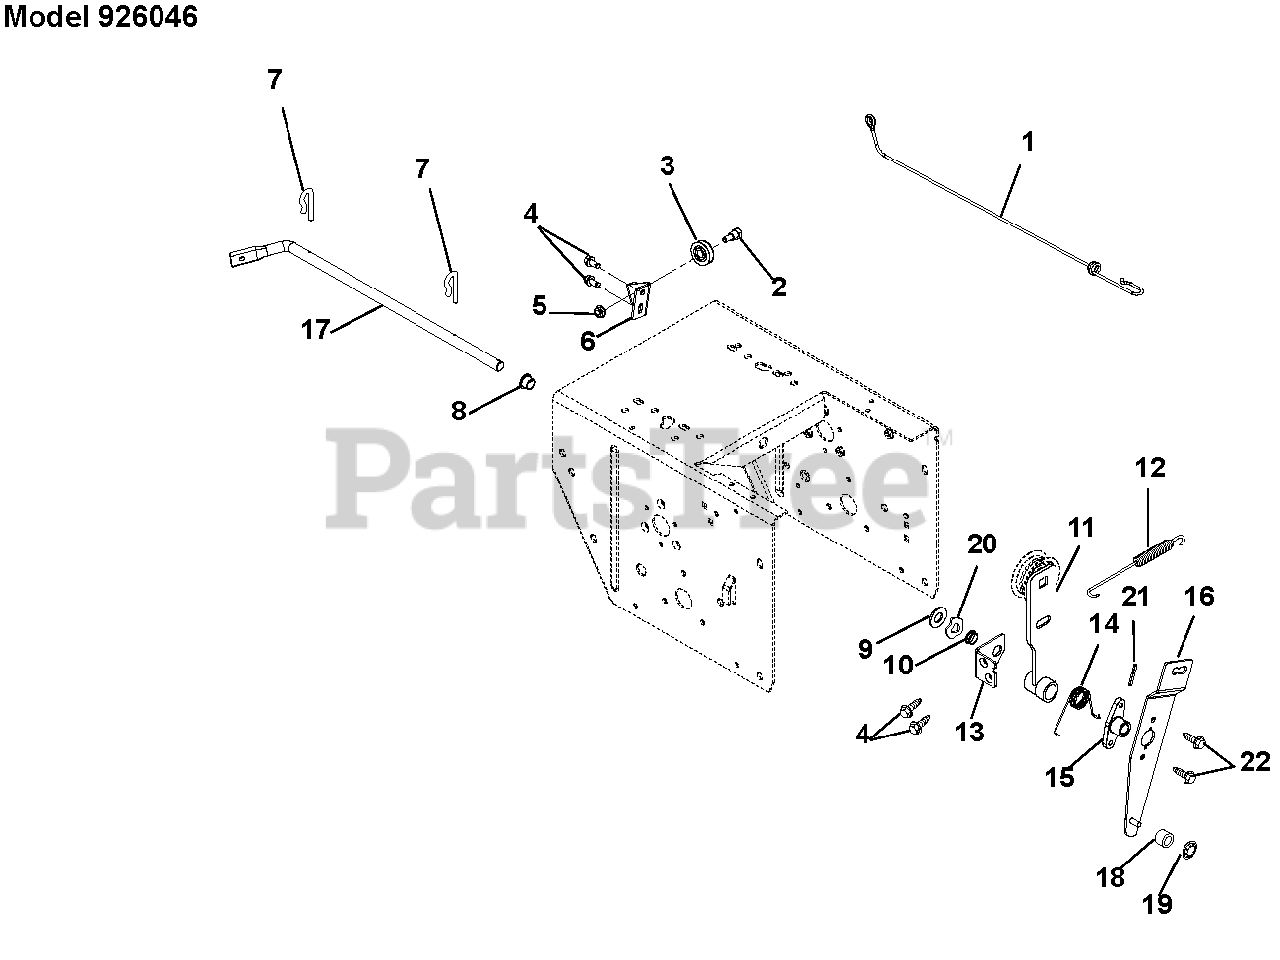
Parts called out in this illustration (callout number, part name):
2	Bolt, Shoulder
3	Pulley, Cable
4	Screw, Tapping Hex Washer Head Thread Rolling .25-20 x .50
5	Nut, Locking Top Flange .25-20
6	Bracket, Cable Pulley
7	Clip, Spring
8	Bushing, Polyliner
9	Washer, Flat Steel .531 x 1.06 x .095
10	Bushing, Polyliner
11	Arm, Idler – Traction
13	Bracket, Support
15	Hub, Brake Arm
16	Arm, Idler – Attachment
17	Arm, Attachment
18	Bushing,Sleeve
19	Ring, Retaining External .250 x .010
20	Wave Washer
21	Pin, Roll .125 x 1.00
22	Screw, Tapping Hex Washer Head Thread Rolling .25-20 x .75
